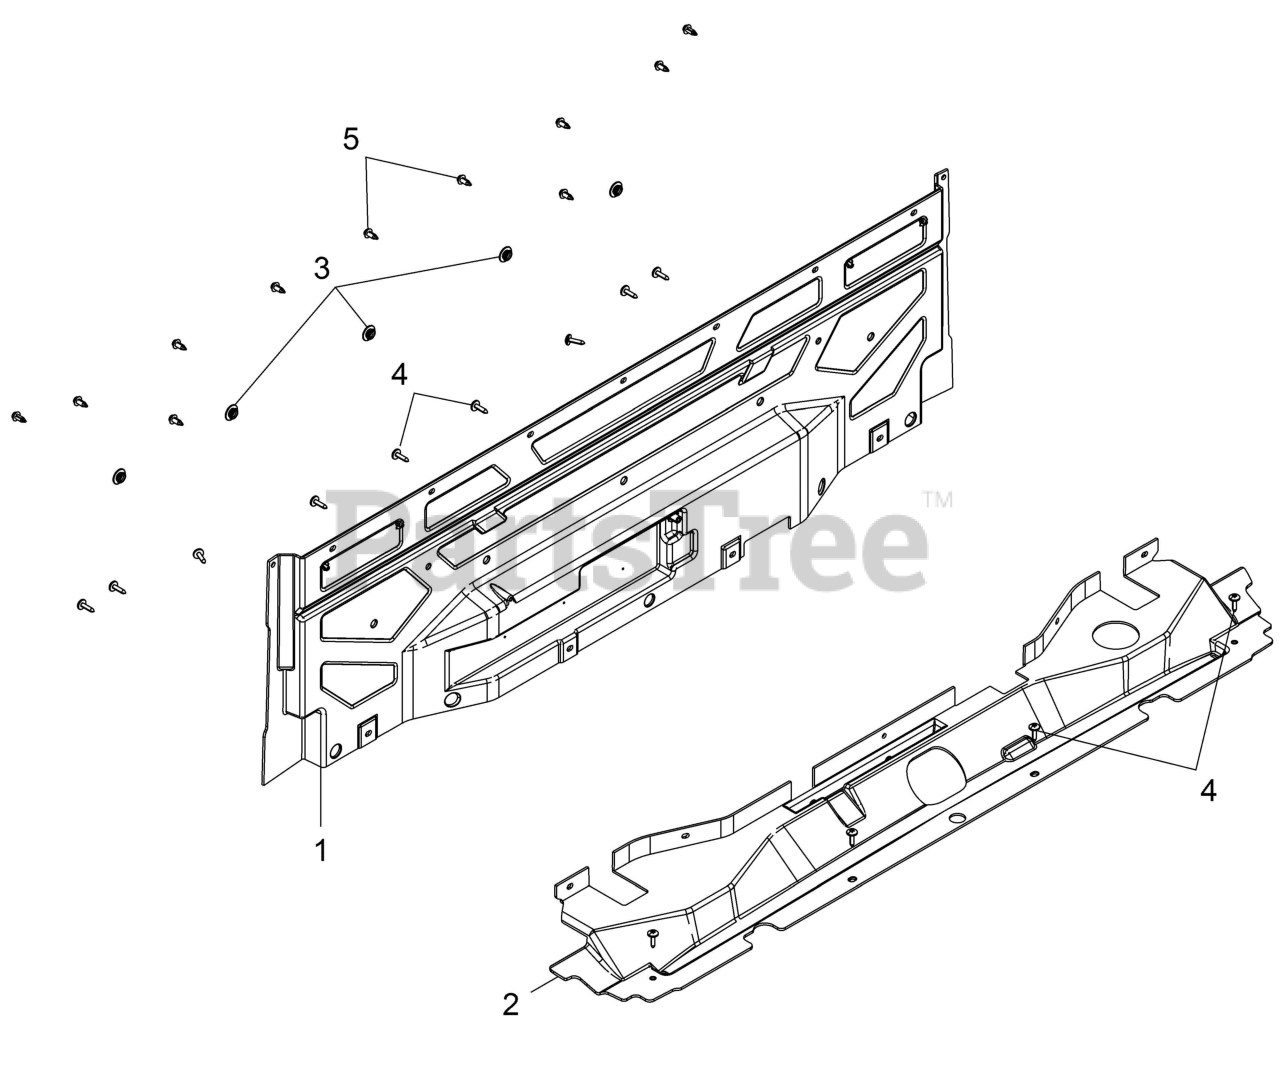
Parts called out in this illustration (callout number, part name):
1	PANEL, CLOSEOFF, REAR, BLK
2	PANEL-CLOSEOFF,LOWER,BLK
3	PLUG-COMPARTMENT
4	SCR-TXTH-M6X1.0X25 RIE
5	RIVET-TUFLOK,.315-.325X.787 (5
